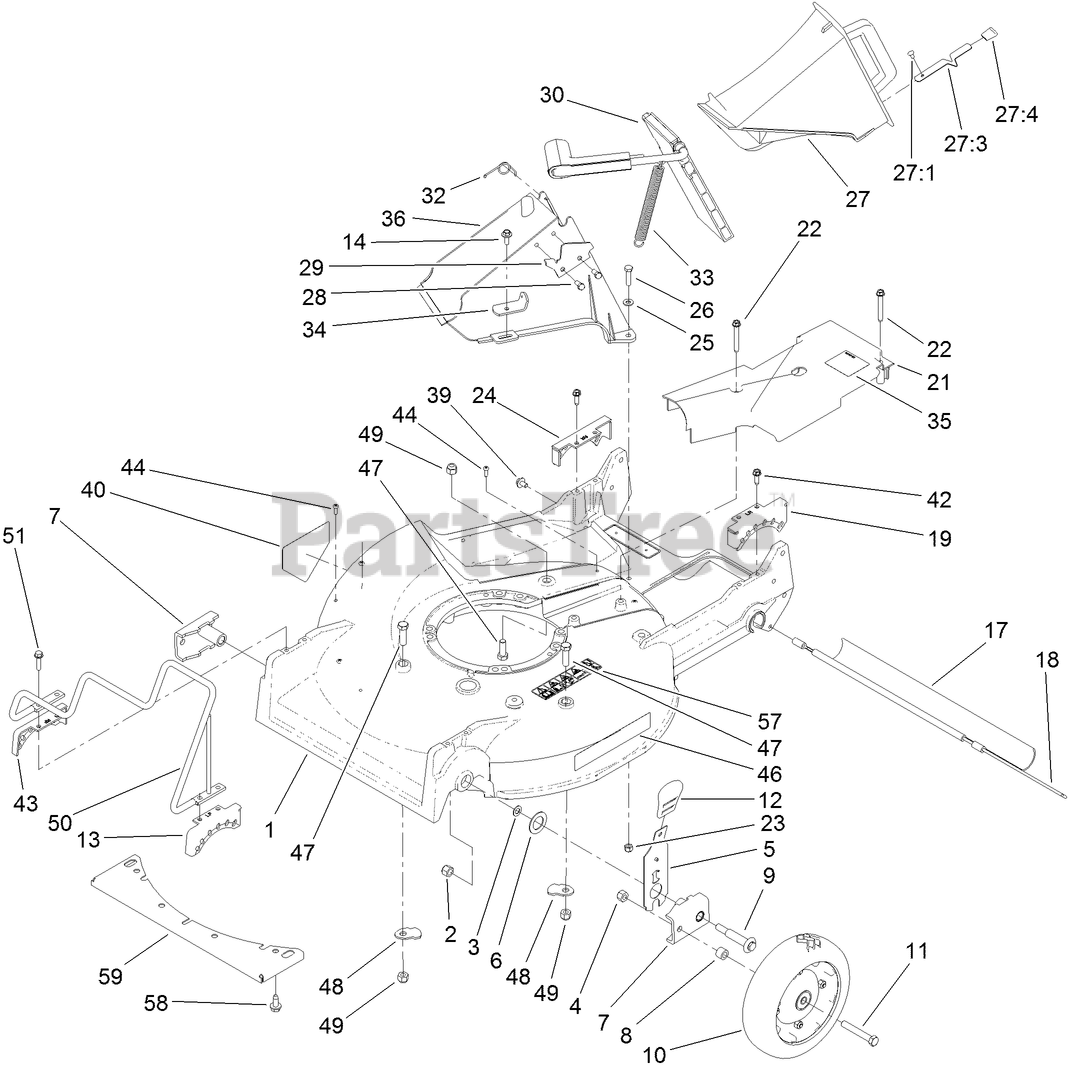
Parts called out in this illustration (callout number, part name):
1	HOUSING
2	NUT-LOCK
3	WASHER
4	NUT-LOCK, CONE
5	FRONT SPRING ARM ASM
6	WASHER-THRUST
7	ARM-PIVOT, FRONT
8	SPACER-WHEEL
9	SCREW-SHOULDER
10	WHEEL AND TIRE ASM
11	SCREW-HH
12	KNOB-HOC
13	QUADRANT-FRONT, LH
14	SCREW-HWH
17	SHIELD-TRAILING
18	ROD-SHIELD
19	QUADRANT-REAR, LH
21	COVER-BELT
22	SCREW-HWHTF
23	NUT-LOCK, NI
24	QUADRANT-REAR, RH
25	WASHER-FLAT
26	SCREW-HH
27	DISCHARGE PLUG ASM
27:1	RIVET-HEAD, FLAT
27:3	LATCH-PLUG, DISCHARGE
27:4	GRIP-LATCH
28	SCREW-PLASTITE
29	LATCH-PLATE
30	DISCHARGE DOOR ASM
32	RETAINER-DOOR
33	SPRING-DOOR
34	BRACKET-SPRING
35	DECAL-GREASE
36	TUNNEL-DISCHARGE
39	SCREW AND WASHER ASM
40	DECAL-DANGER
42	SCREW-HWHTF
43	QUADRANT-FRONT, RH
44	SCREW-PPH
47	SCREW-HH
48	SHIELD-RETAINER
49	NUT-LOCK, NI
50	GUARD-ENGINE
51	SCREW-HWHTF
57	DECAL-DANGER
58	SCREW-HWHTF
